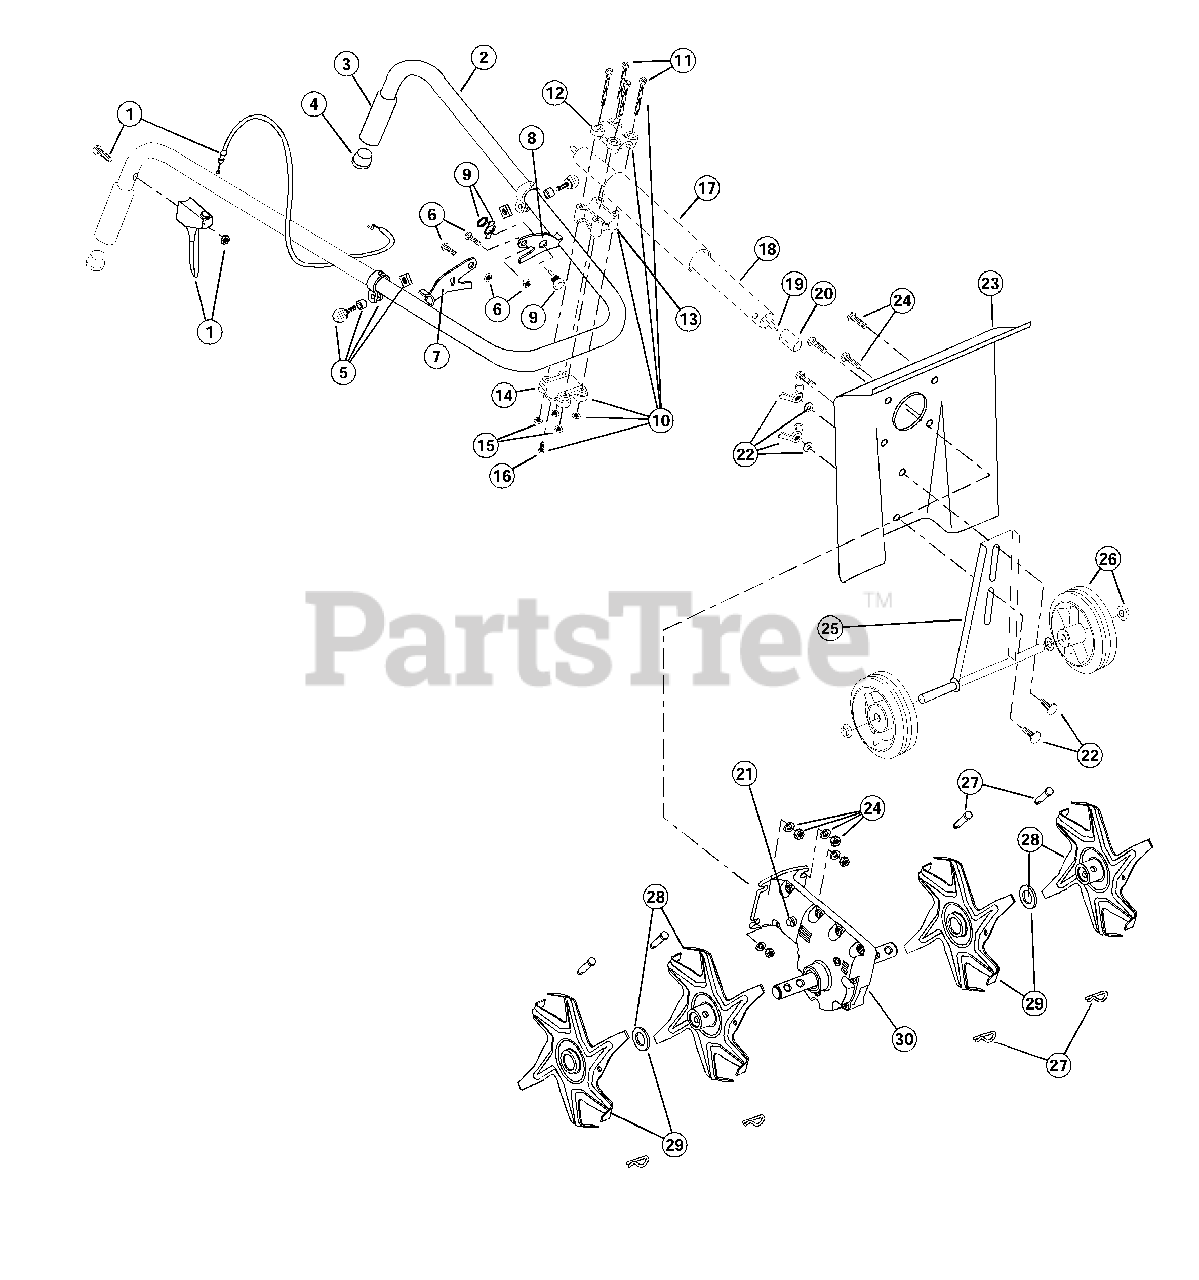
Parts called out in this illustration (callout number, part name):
1	Throttle Trigger and Cable Assembly
2	Handle Bar w/Clamp Assemblies
4	Tube Closure
5	Clamp Assembly
6	Engine Bracket Mounting Hardware
7	Engine Mount Bracket, R.H.
8	Engine Mount Bracket, L.H.
9	Switch Assembly
10	Handle Bracket Assembly
12	Upper Handle Clamp
13	Middle Handle Clamp
14	Lower Handle Clamp
16	Anti-Rotation Screw
18	Drive Shaft Housing Assembly
19	Flexible Drive Shaft
20	Retainer Sleeve
21	Sleeve Retainer Bolt
22	Wheel Bracket Mounting Hardware
24	Guard Mounting Hardware
25	Wheel Bracket Assembly
26	Wheel Assembly
27	Tine Fastener Assembly
28	Tine Assembly (Left Outer or Right Inner)
29	Tine Assembly (Left Inner or Right Outer)
30	Gear Box Assembly
